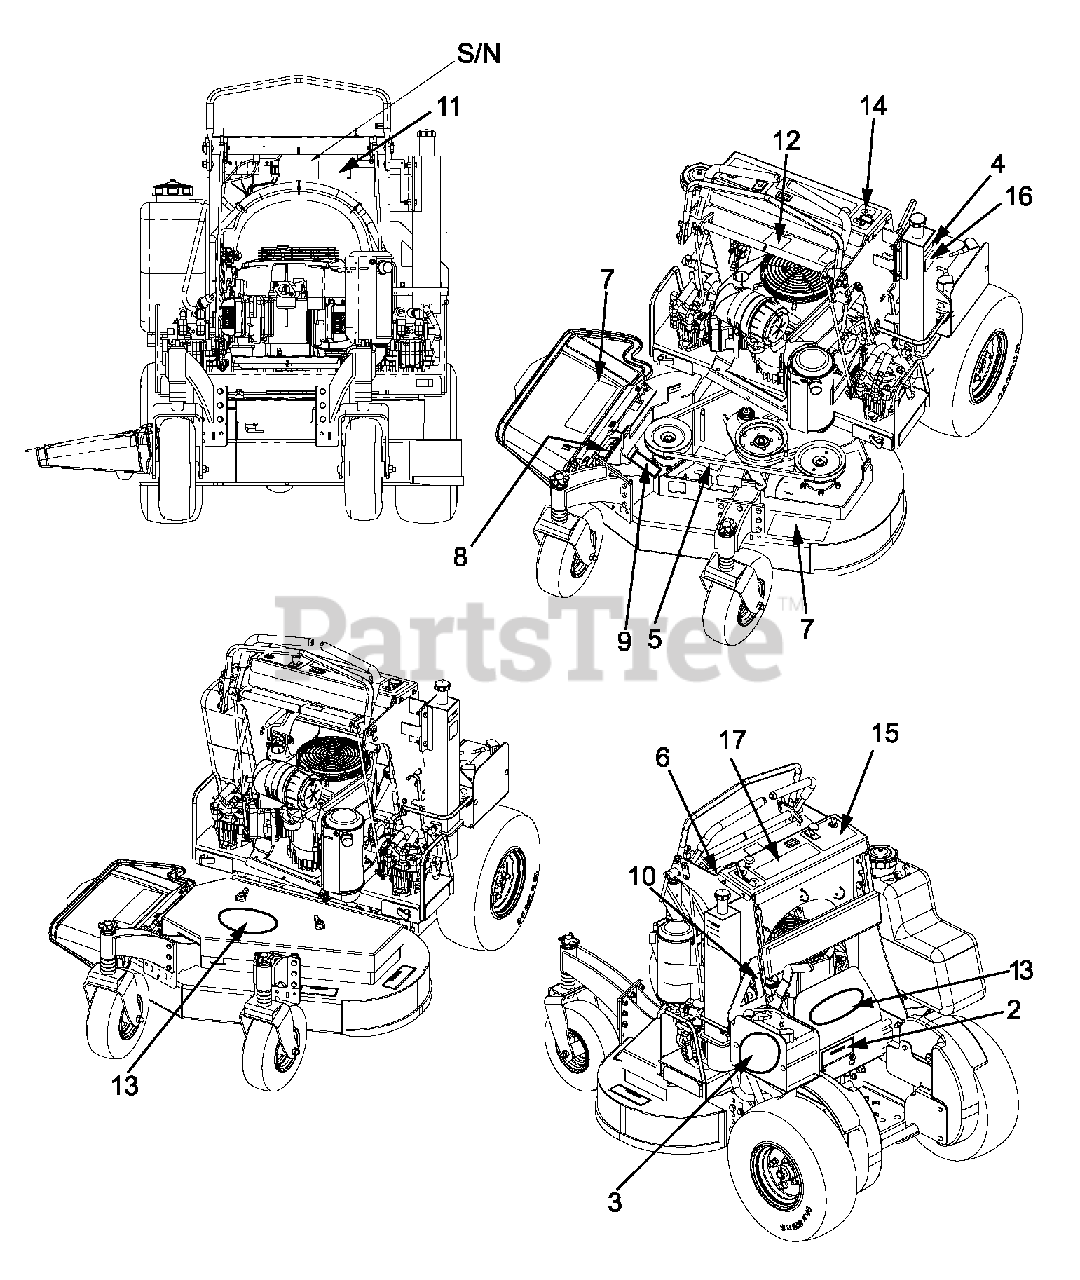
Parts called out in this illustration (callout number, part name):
1	Decal, Prostance 1934 FX
2	Decal, Debris
3	Dun-Lap MFG
4	Label, Warning (Hot Surfaces)
5	Decal, Belt Routing
6	Decal, Warning - Slope
7	Decal, Mower Pan Danger
8	EZT Zero Turn Decal Small
9	Decal, Warning - Shield
10	Label - Park Brake Direction
11	Decal Patent
12	Decal, Direectional Control
13	Manual, owners- Gravely Brush
14	DECAL, THROTTLE
15	DECAL, PTO & KEY SWITCH
16	Decal, Hydro Oil Specs
17	DECAL, GENERAL CAUTION
